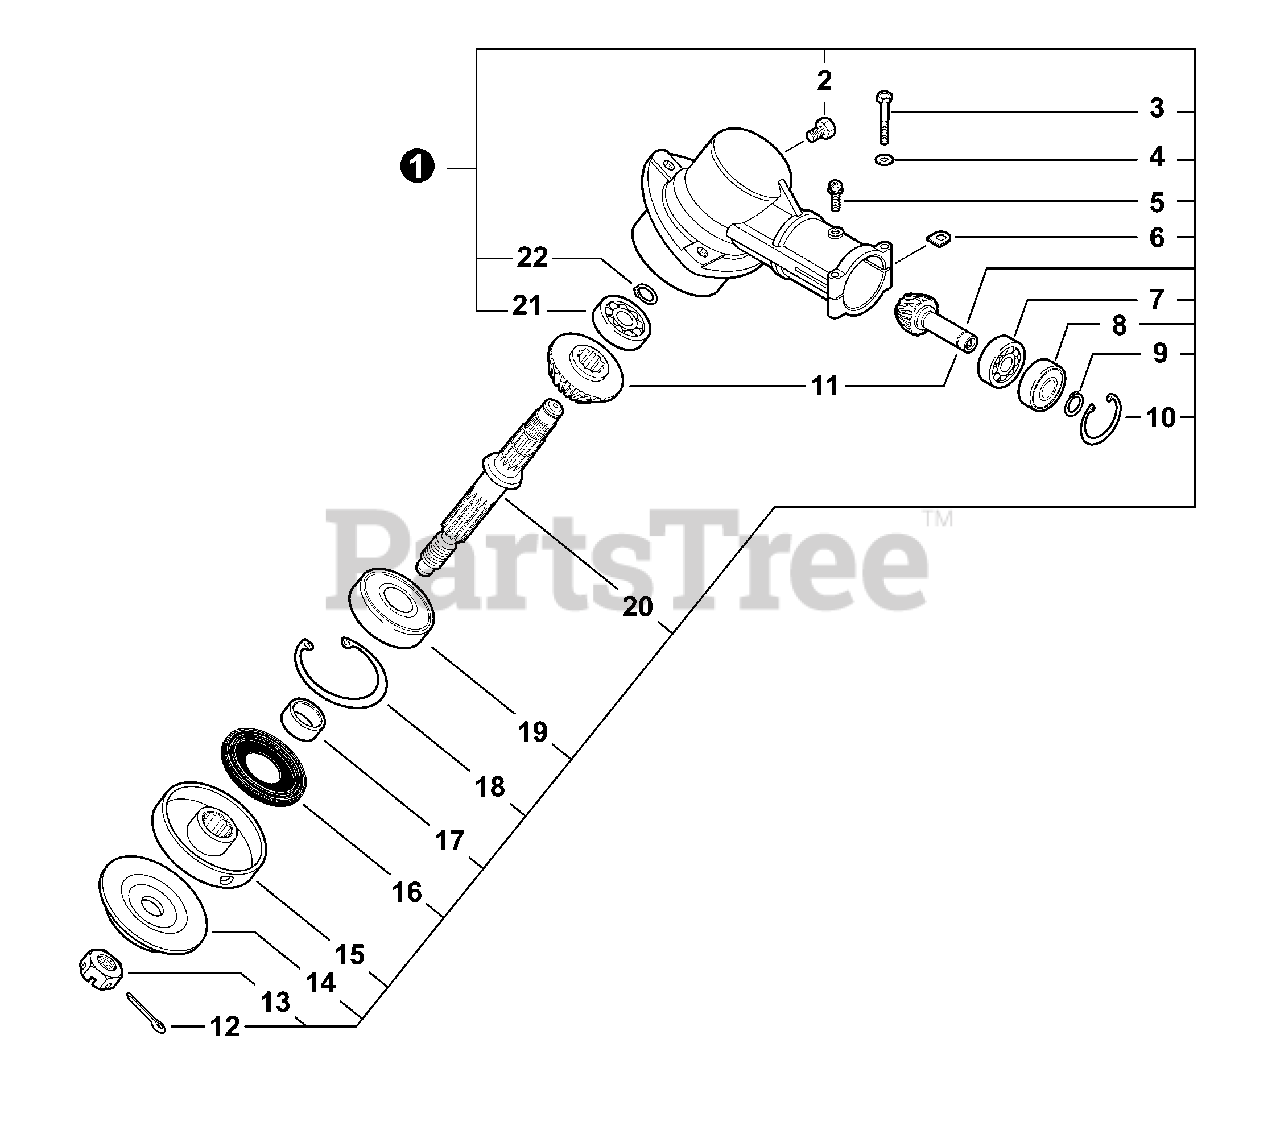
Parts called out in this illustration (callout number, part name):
1	GEAR CASE ASSY
2	BOLT - 8×8
3	BOLT - 5×35
4	WASHER - 5
5	SCREW - 5×10
6	WASHER, SHIM
7	BEARING, BALL - 6900
8	BEARING, BALL - 6900Z
9	RING, RETAINING - 10
10	RING, RETAINING - 22
11	GEAR SET - BEVEL
12	PIN, SPLIT - 2×22
13	NUT - 10 -- LEFT HAND
14	ADAPTER, BLADE - LOWER
15	ADAPTER, BLADE - UPPER
16	SEAL, OIL
18	RING, RETAINING - 32
19	BEARING, BALL - 6201
20	GEAR, SHAFT
21	BEARING, BALL - 609
22	RING, RETAINING - 12
